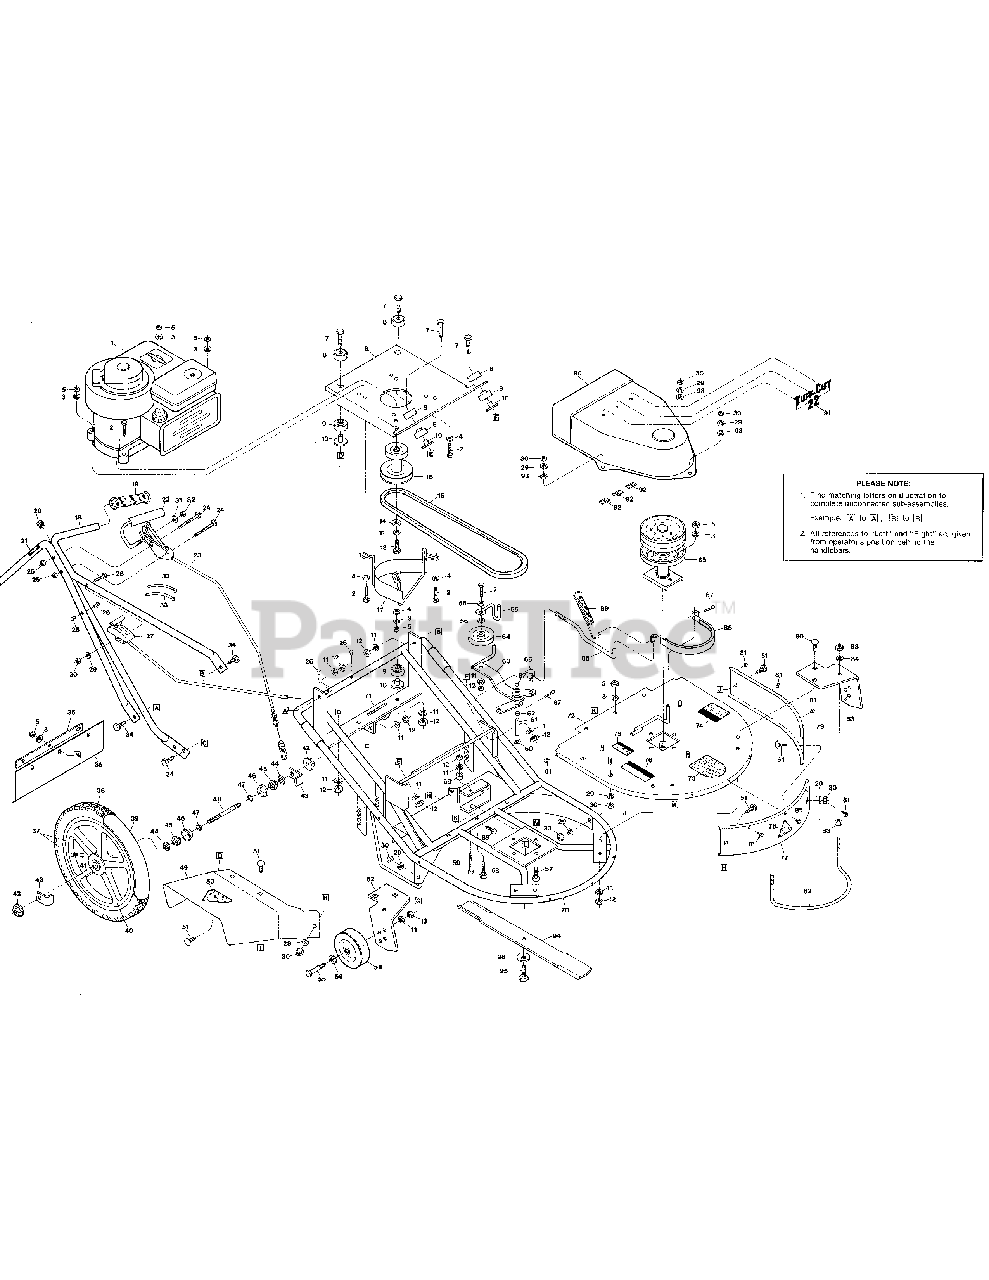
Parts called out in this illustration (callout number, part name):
2	SCR-HH 5/16-18X1.75
3	WASHER-LK .312
4	WASHER-.88X312X.08
5	NUT-HEX 5/16-18
6	BASE-ENGINE
7	SCR-HH 3/8-16X2.0 G5
8	REBOUND MOUNT-24"
9	LOAD CARRYING MOUNT-24"
10	TUB-SPACER 24"
11	WASHER-LK .375
12	NUT-HEX 3/8-16
13	SCR-HH 3/8-24X1.25 GR5
14	WASHER-1.0X.438X.104
15	BLADE-V BELT
16	PULLEY-ENGINE
17	GUIDE-BELT PNT
18	ASSM-HANDLEBAR 22" PUSH (INCL. 19 & 21)
19	GRIP-HANDLEBAR
20	PLUG-METAL CAP
21	DECAL-STARTING INST
22	BAIL WELDMENT-PUSH MOWER
23	CABLE-BLADE DRIVE (CABLE & LATCH)
24	SCR-PHP M10-24X3.0
25	NUT-HEX LOCK #10-24 PL
26	PLUG-HOLE
27	SPEED CONTROL-ENGINE (CABLE & CONTROL)
28	SCR 1/4-20X1.5 PL CSHH
29	WASHER-LK .25
30	NUT-HEX 1/4-20
31	WASHER-FLAT 5/16 SAE
32	NUT-H/LK 5/16-18
33	TIE-RED
34	SCR-HH 3/8-16X.75 G5
35	BRKT-PROT TRAILER PNT
36	TRAILER-MOWER
37	ASSM-TIRE & WHEEL (INCL. 38-42,44-48)
38	TIRE-16 X 2.125
39	TUBE-16"
40	ASSM-16" RIM
41	CAP-VALVE
42	NUT-HF/LK 3/8-24 WHIZ
43	TAB-WHEEL LOCK 22"
44	NUT-LOCK 3/8-24 PL
45	NUT-ACORN 3/8-24
47	BEARING-WHEEL
48	AXLE-WHEEL
49	CHUTE-DISCHARGE W/DECAL (INCL. 50)
50	DECAL-BLADE WARNING
51	SCR-CARR 1/4-20X.375
52	HANGER-RT WHL PNT
53	HANGER-LT WHL PNT
54	ASSM-TIRE&WHEEL 6X1.50
55	SCR-SHLDR 3/8-16X1.406
56	WASHER-FLAT 3/8 SAE
57	SCR-HH 5/16-18X1.0 G5
58	SCR-HH 5/16-18X1.625 G5
59	SCR-HH 3/8-16X4.5 G5
60	SHIM-WASHER
61	TUBE-PIVOT
62	BEARING-SLEEVE
63	ARM-IDLER W/BUSHINGS (INCL. TWO BEARINGS, #62)
64	PULLEY-IDLER
65	GUIDE-BLADE BELT
66	TRUNNION
67	PIN-COTTER .094X1.0
68	SPACER-.625X.387X1.0
69	SCR-HHC 5/16-18X.75 GR 5
70	WELDMENT-FRAME 22" (INCL. 71)
71	DECAL-CPSC COMPLIANCE
72	ASSM-DECK TOP 22" (INCL. 73-76)
73	DECAL-TUFFCUT LOGO
74	DECAL-WARNING PROCEDURES
75	DECAL-CAUTION BELT COVER
76	DECAL-DANGER GUARD
77	WRAP-FRONT 22" PNT (INCL. 78)
79	WRAP-LH PNT
80	SCR-CARR 3/8-16X1.00
81	SCR-HW M10-16X.75 SELT DR
82	BUMPER-22" PNT
83	NUT-HEX JAM 1/2-13
84	WASHER-LK .5
85	KIT-SPINDLE TUFFCUT I&II
86	BRAKE BAND & LINING (W/LINING)
87	PIN-COTTER .125X.750
88	ROD-BRAKE ENGAGEMENT
89	SPRING-SPINDLE BRAKE
90	COVER-BELT 22"PUSH MOWER
91	PLATE-NAME 22"
92	RING-PUSH ON
93	WASHER-FLAT 1/4 SAE
94	BLADE-22" TUFFCUT NLA ETION
95	SCR-HH 3/8-24 X 1.5" G8
96	WASHER-BELLEVILLE 3/8
